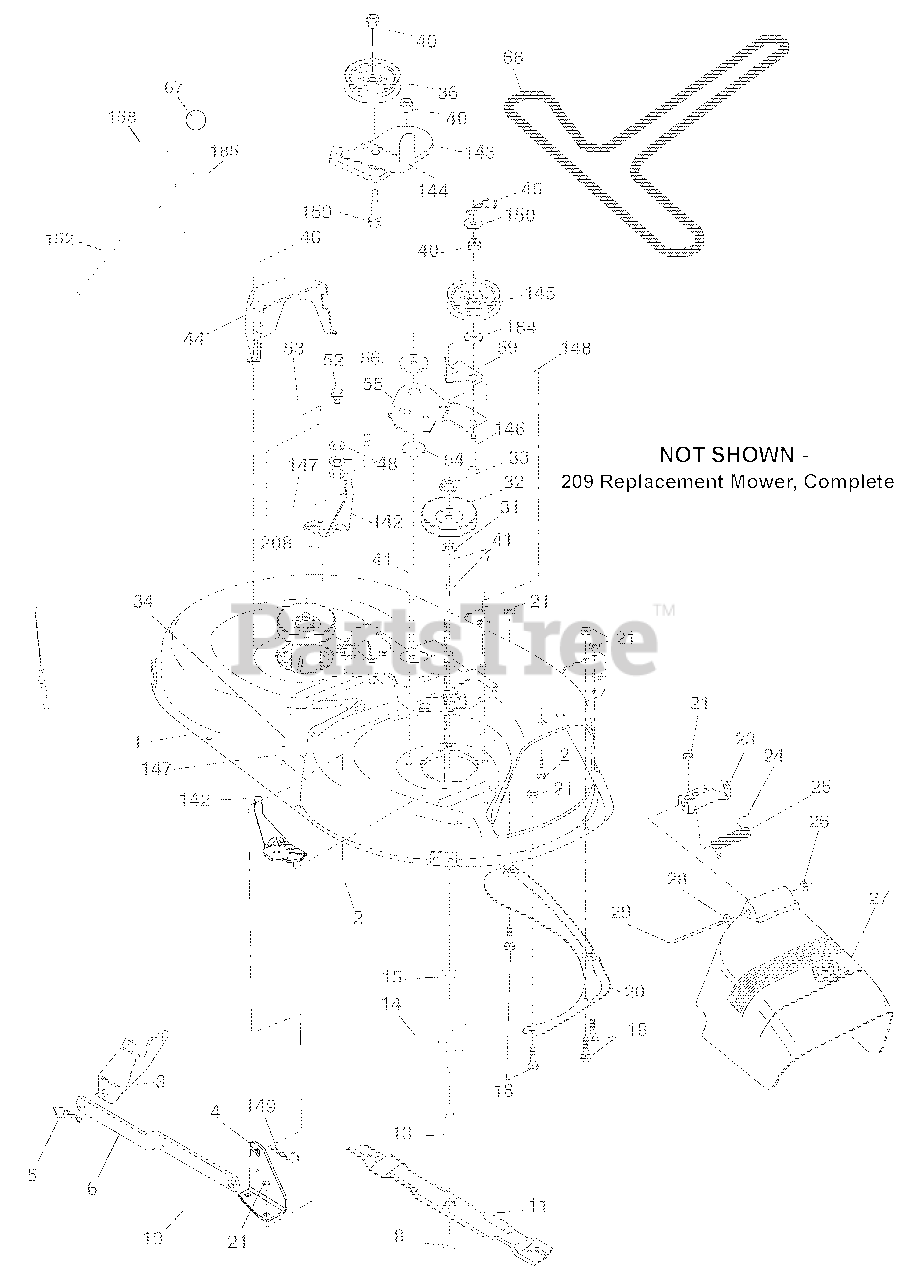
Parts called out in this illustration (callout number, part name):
1	MOWER DECK ASSEMBLY, 42"
3	Bracket Asm Fr. Sway Bar 3/42
4	Bracket Asm Deck 42" Sway Bar
5	RETAINER.SPRING
6	Bar Sway Deck
8	BOLT/WASHER ASM.7/16-20.UNF
11	BLADE.MOWER.42"HI LIFT PREMIUM
13	SHAFT ASM.MNDRL.N/GREASEABLE38
14	HOUSING.MANDREL.4PT.SERVICE
15	BEARING.BALL.MANDREL
18	BOLT.RDHD.SQNK.5/16-18 X 5/8
19	Bolt, Shoulder
20	BAFFLE.VORTEX.42.STD/HEAVY DTY
21	Nut, Hex, Crownlock 5/16-18
23	Bracket, Deflector Mower 42"
24	CAP.SLEEVE..80X.112.BLK.MOWER
25	SPRING.TORSION
26	NUT.PUSH.PHOS.& OIL
27	SHIELD
28	Washer 11/32 x 5/8 x 16 Ga.
29	ROD.HINGE.42/46"
31	WASHER.SPACER.MANDREL
32	MANDREL.PULLEYS.42,44,50
32	MANDREL ASM.SUB.N-GRS.4 BOLT
32	AND BEARING ONLY (KEY #15)-PULLEY/NUT/WASHER AND BLADE BOLT/WASHERS NOT INCLUDED)
33	NUT.FLANGE.LOCK.TOP
34	BOLT.CARR.SH.3/8-16X1-1/2.GR5
36	PULLEY, IDLER, FLAT
40	Nut, Hex, Flangelock 3/8-16
41	HEX HEAD BOLT
44	Guard, Mandrel, LH
45	RETAINER SPRING
46	SCREW.THD.ROLL.1/4-20 X 5/8
48	Washer, Hardened
52	Bolt, Shoulder 5/16-18 unc
53	Arm Assembly, Pad, Brake
54	WASHER.FLAT.HARDENED
55	Arm, Idler
59	GUARD.TUV.IDLER
67	Knob Round
68	V-Belt, 42" Mower
142	Anchor Spring Brake Mower
143	Bracket Arm Idler 42"
144	KEEPER.BELT
145	PULLEY IDLER FLAT
146	Bolt Carriage Idler
147	Spring Extension
148	Spring Return Idler
149	Retainer Spring Yellow
150	WASHER.9/32 X 3/4 X 10 GA.
152	Clutch Cable 42"
158	Screw 1/4-20 x 1/2
159	Bolt Rdhd Sqn 3/8-16 unc x 1-3
184	Washer 13/32 x 7/8 x 10 Ga.
185	Head Asm Cable Clutch\
208	SCREW.THDROL.3/8-16X1/2.TYT.BL
209	REPLACEMENT MOWER
